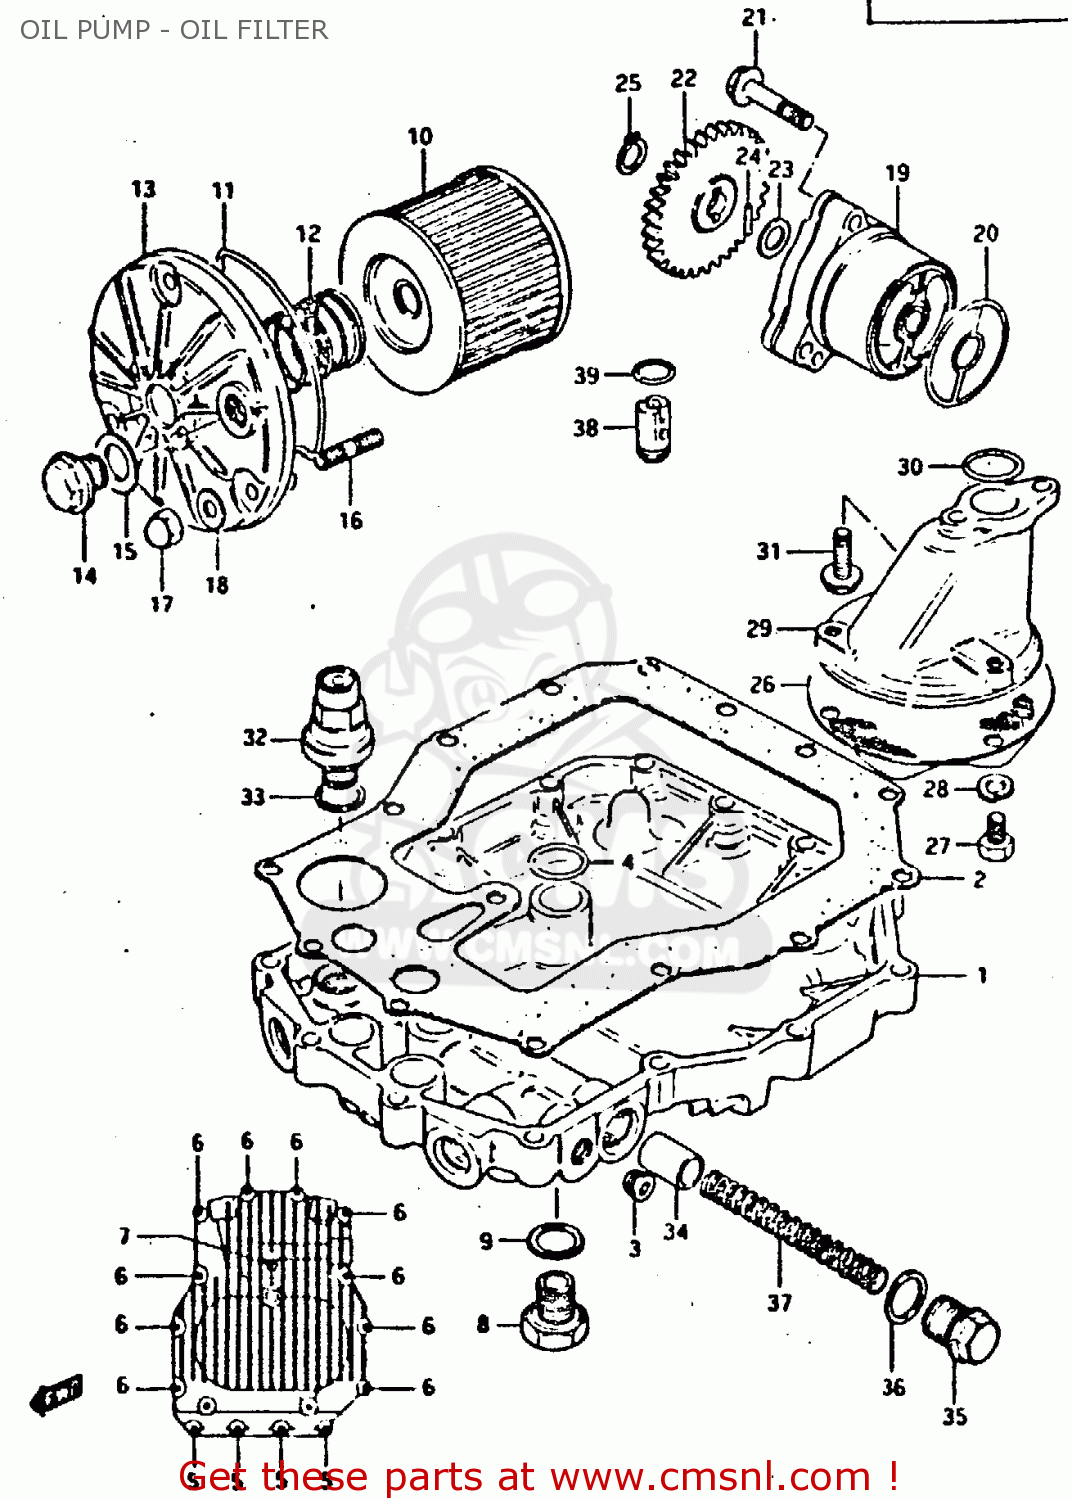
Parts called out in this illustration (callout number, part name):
1	PAN,OIL
2	GASKET,OIL PAN
3	PLUG
4	O RING(D:3.2,ID:17.8)
5	BOLT (6*25)
6	BOLT (6*30)
7	BOLT (6*35)
8	PLUG (14X12)
9	GASKET(14X19.2X2) (NAS)
10	FILTER ASSY,ENGINE OIL
11	O RING,OIL FILTER CHAMBER CAP
12	SPRING
13	CAP,OIL FILTER
14	PLUG (14X12)
15	GASKET(14X19.2X2) (NAS)
16	STUD 6X20
17	NUT
18	WASHER
19	PUMP ASSEMBLY,OIL
20	O-RING,OIL PUMP
21	BOLT
22	GEAR,ENG OIL PUMP DRIVEN(NT:33
23	SHIM
24	PIN(4X15.8)
25	CIRCLIP
26	STRAINER,ENGINE OIL
27	BOLT
28	LOCK WASHER
29	PROTECTOR,OIL STRAINER
30	O RING(D:3.2,ID:17.8)
31	BOLT,REAR
32	REGULATOR ASSY,ENGINE OIL
33	WASHER
34	PLUNGER,CONTROL
35	PLUG
36	GASKET(16X22X2) (NAS)
37	SPRING
38	VALVE ASSEMBLY,PISTON OIL
39	O RING(D:1.3,ID:9.8)
